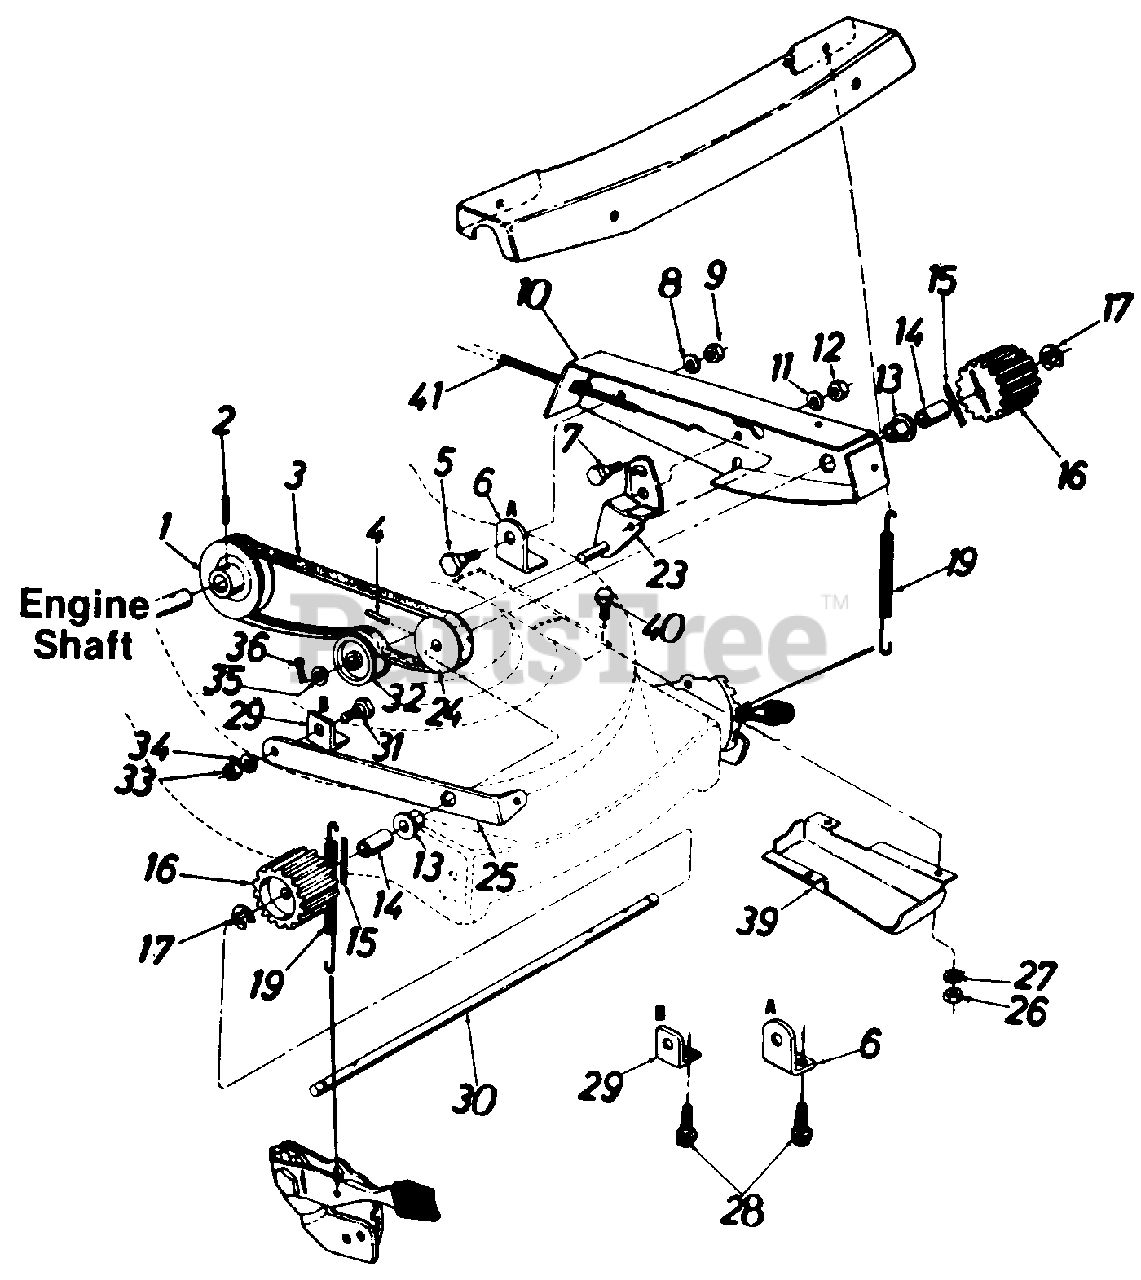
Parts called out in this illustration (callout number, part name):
1	1/2 "V"-Engine Pulley
2	Spring Pin Spiral 3/16" Dia. x 1."5" Lg.
3	"V"-Belt 1/2" x 28.0" Lg.
4	Spring Pin Spiral 3/16" Dia. x 1.00" Lg.
5	Shld. Bolt .500 Dia. x .170
6	Belt Cover Pivot Brkt.
7	Shld. Bolt .500 Dia. x .170
8	L-Wash. 3/8" I.D.
9	Hex Jam Nut 3/8-16 Thd.
10	Belt Cover Ass'y.
11	L-Wash. 3/8" I.D.
12	Hex Jam Nut 3/8-16 Thd.
13	Hex Flange Brg. .503 I.D.
14	Spacer .52 I.D. x .69 O.D. x .88
15	Spring Pin Spiral 3/16 Dia. x 1.25" Lg.
16	13 Teeth Drive Pinion
17	"E"-Ring for .500 Dia. Shaft
19	Extension Spring .40 O.D. x 3.25" Lg.
23	Idler Brkt. Ass'y.
24	1/2"V"-Pulley
25	Cover Support Brkt.
26	Hex Nut 1/4-20 Thd.*
27	L-Wash. 1/4" I .D. *
28	Hex Wash. Hd. Self-Tap Sc 1/4-20 x .50" Lg.
29	Cover Support Pivot Brkt.
30	Pinion Shaft
31	Shld. Bolt .500 Dia. x .170
32	Plastic Flat Idler
33	Hex Jam Nut 3/8-16 Thd.*
34	L-Wash. 3/8" I.D.*
35	Fl-Wash. .53 I.D. x .93 O.D.
36	Cotter Pin 1/8" Dia. x 1.00" Lg. *
39	Belt Cover Baffle
40	Truss Mach. Scr. 1/4-20 x .50" Lg.*
41	S.P. Cable x 53.0"-Yellow
